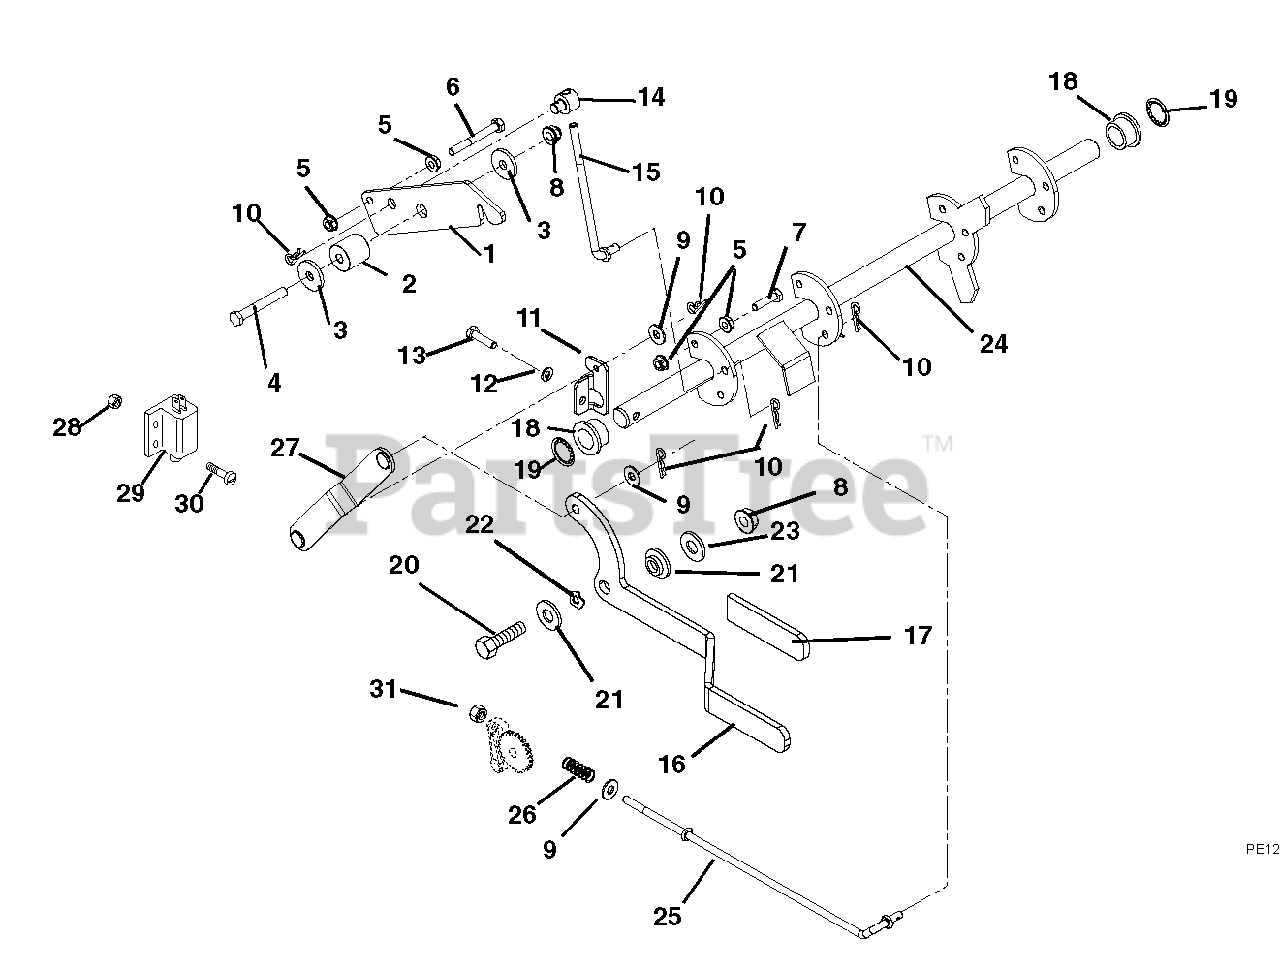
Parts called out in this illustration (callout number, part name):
1	Latch, Neutral
3	Washer, Flat Steel .344 x 1.125 x .135
4	Bolt, Hex .31-18 x 2.25 Grade 5
5	Nut, Locking Flange .250-20
6	Bolt, Hex .25-20 x 2.25 Grade 5
7	Bolt, Hex .25-20 x 1.00 Grade 5
8	Nut, Flange Nyloc 5/16-18
9	Washer, Flat Steel .312 x .734 x .065
10	Pin, Hair Internal .08 x .18 x 1.18
11	Crank, Parking Brake
12	Washer, Locking .25 x .062 Regular
13	Bolt, Hex .25-20 x 1.00 Grade 5
14	Trunnion, Brake
15	Brake, Link
16	Handle, Parking Brake
17	Grip, Parking Brake
18	Bushing, Flanged .750 x 1.000 x .625 x 1.250
19	Push Nut, .745 Shaft
20	Bolt, Hex .31-18 x 1.75 Grade 5
21	Bushing, Flange .325 x .501 x .250 x 1.12
22	Washer, Wave .50 x .75 x .015
23	Washer, Flat Steel, .328 x .87 x .179
24	Weldment, Brake Shaft
25	Rod, Brake
26	Spring, Compression .045 x .50 x 1.187
27	Link, Parking Brake
28	Nut, Locking Nylon 10-24 with Insert
29	Switch, Double Pole
30	Screw, Machine 10-24 x .75
31	Nut, Locking-Nylon .250-20
32	Kit, Brake
